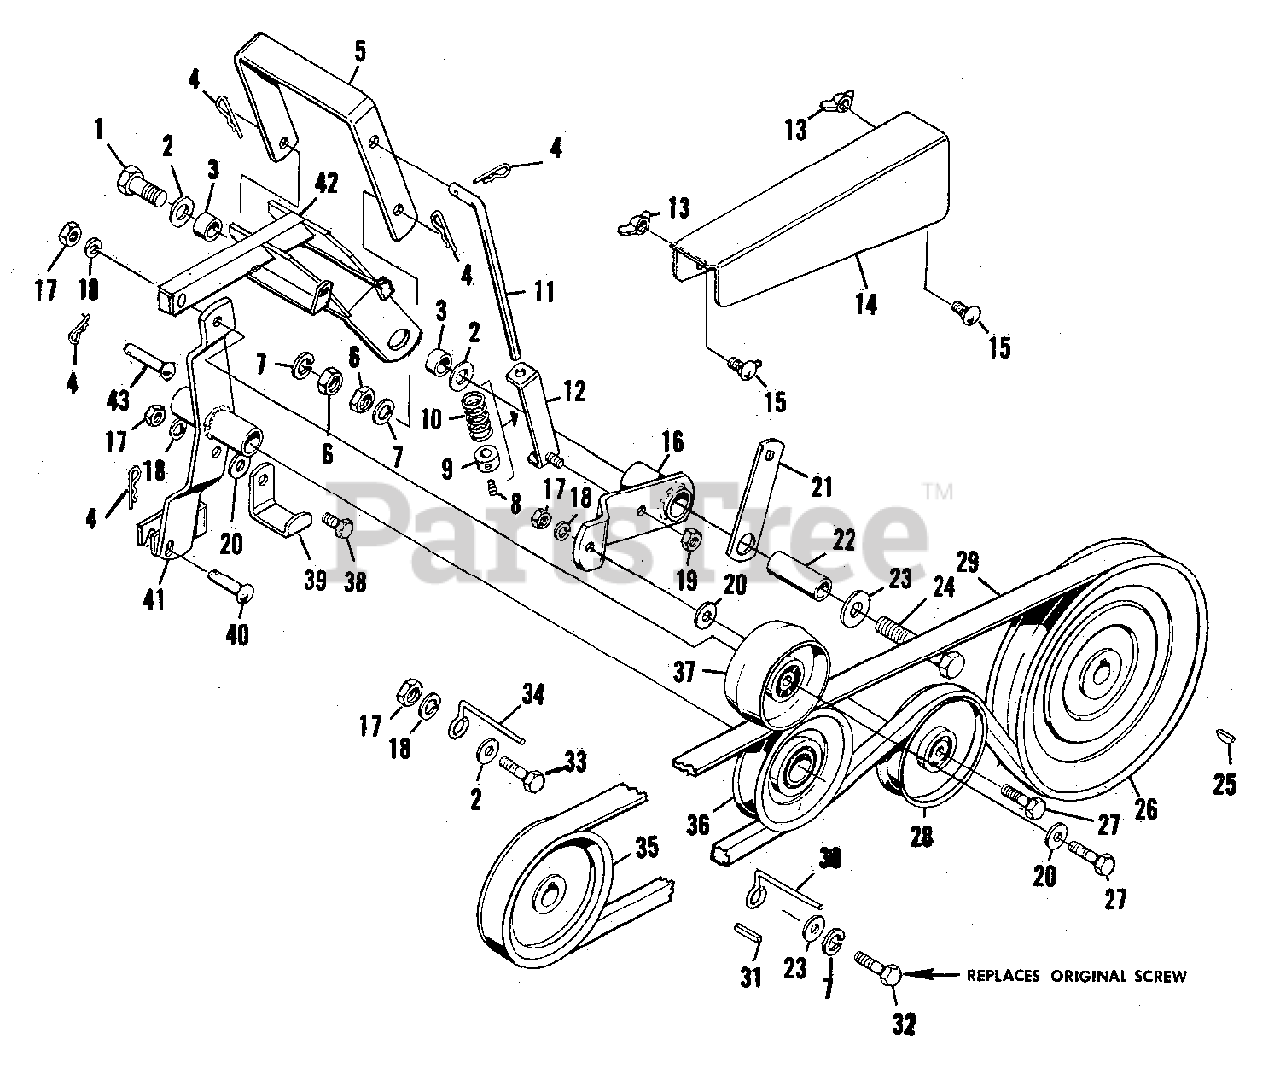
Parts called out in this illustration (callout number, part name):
1	SCREW, Hex Cap, 7/16-14 x 1-1/4
2	WASHER, Flat, 3/8
4	CLIP, Spring
5	HANDLE, Clutch
6	NUT, Hex Jam, 7/16-14
7	WASHER, Lock, 7/16
8	SCREW, Set, 1/4-20 x 3/8
12	GUIDE ASSEMBLY, Rod
13	NUT, Wing, 5/16-18
15	BOLT, Carriage, 5/16-18 x 3/4
16	LEVER ASSEMBLY, Clutch
17	NUT, Hex, 3/8-16
18	WASHER, Lock, 3/8
19	NUT, Hex, 5/16-18
20	WASHER, Flat, 5/16
21	SUPPORT, Belt Guard
23	WASHER, Flat, 7/16
24	SCREW, Hex Cap, 7/16-14 x 3-1/2
25	KEY, Woodruff, #9
27	SCREW, Hex Cap, 3/8-16 x 1-1/4
29	BELT, "V", 12 HP
32	SCREW, Hex Cap, 7/16-14 x 1-1/4
33	SCREW, Hex Cap, 3/8-16 x 1
36	PULLEY, Idler
37	PULLEY, Idler
38	SCREW, Hex Cap, 3/8-16 x 7/8
41	ARM ASSEMBLY, Idler
42	BAR ASSEMBLY, Lift
